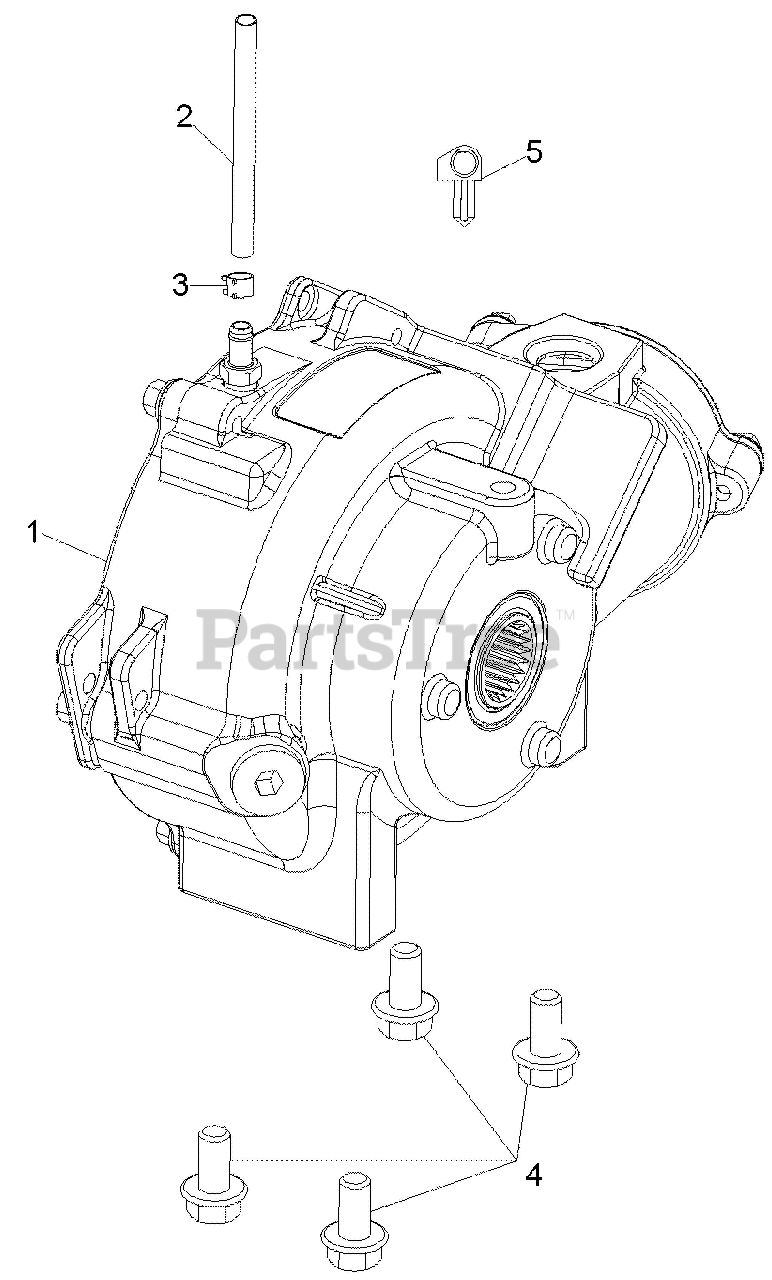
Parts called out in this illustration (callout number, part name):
1	ASM-GEARCASE,FRONT
2	LINE,FUEL,1/4 ID(1525 CM.)
3	CLAMP,HOSE(10)
4	BOLT-M10X1.5X20,HXFLG,W/PATCH
